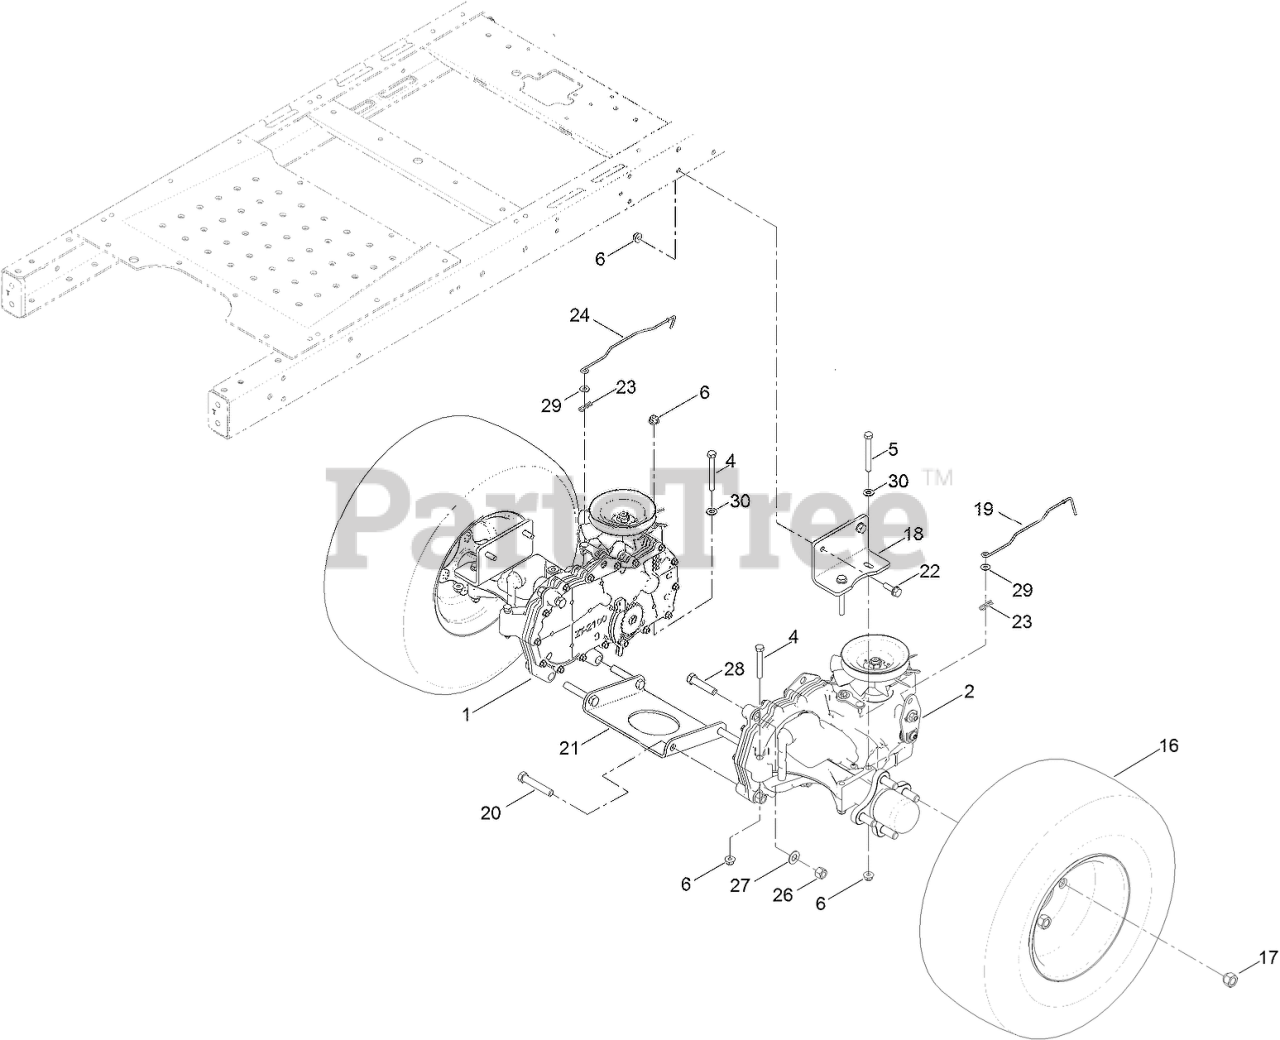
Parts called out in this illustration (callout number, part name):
1	RH HYDRO TRANSAXLE ASM
2	LH HYDRO TRANSAXLE ASM
4	SCREW-HH
5	SCREW-HH
6	NUT-HF, NI
16	2 PLY WHEEL AND TIRE ASM
17	NUT-LUG
18	MOUNT-HYDRO
19	ROD-BYPASS, LH
20	SCREW-HH
21	PLATE-CROSS, HYDRO
22	SCREW-HHF
23	PIN-COTTER
24	ROD-BYPASS, RH
26	NUT-LOCK, NI
27	WASHER-FLAT
28	SCREW-HH
29	WASHER
30	WASHER-PLAIN
